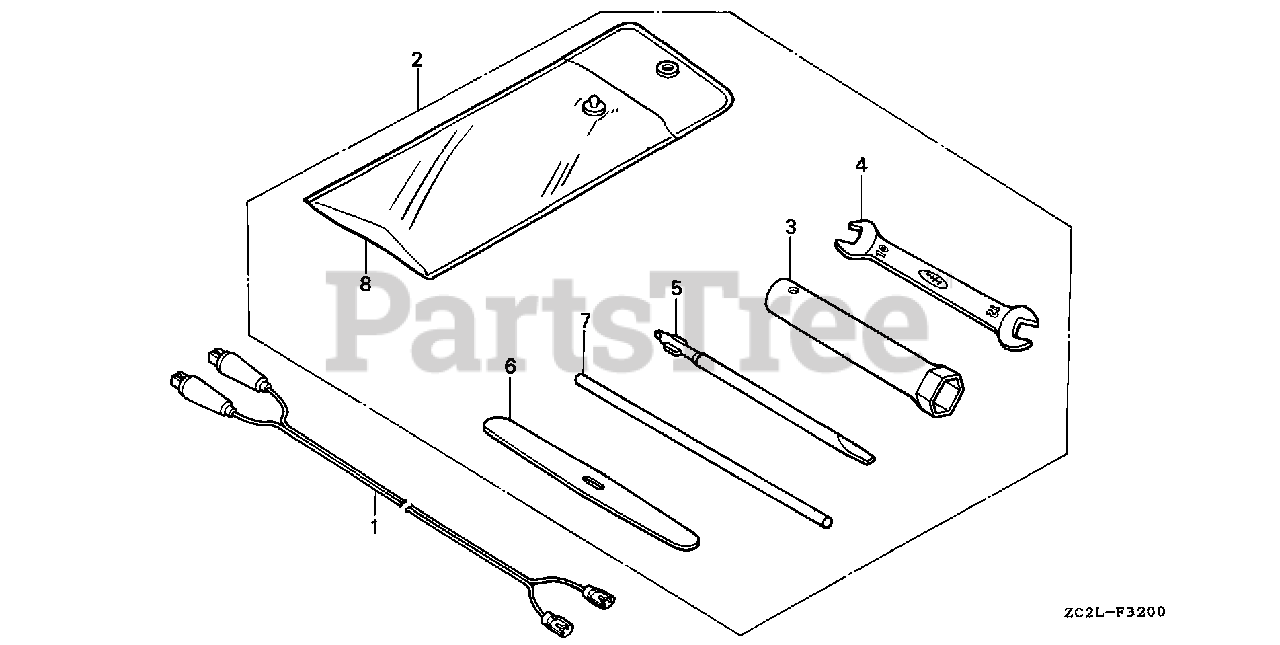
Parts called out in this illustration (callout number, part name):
2	TOOL KIT (NOT AVAILABLE)
3	WRENCH, BOX (P21)
4	SPANNER (10X12)
5	DRIVER 3, MINUS SCREW (NO.2)
7	BAR A, HANDLE
